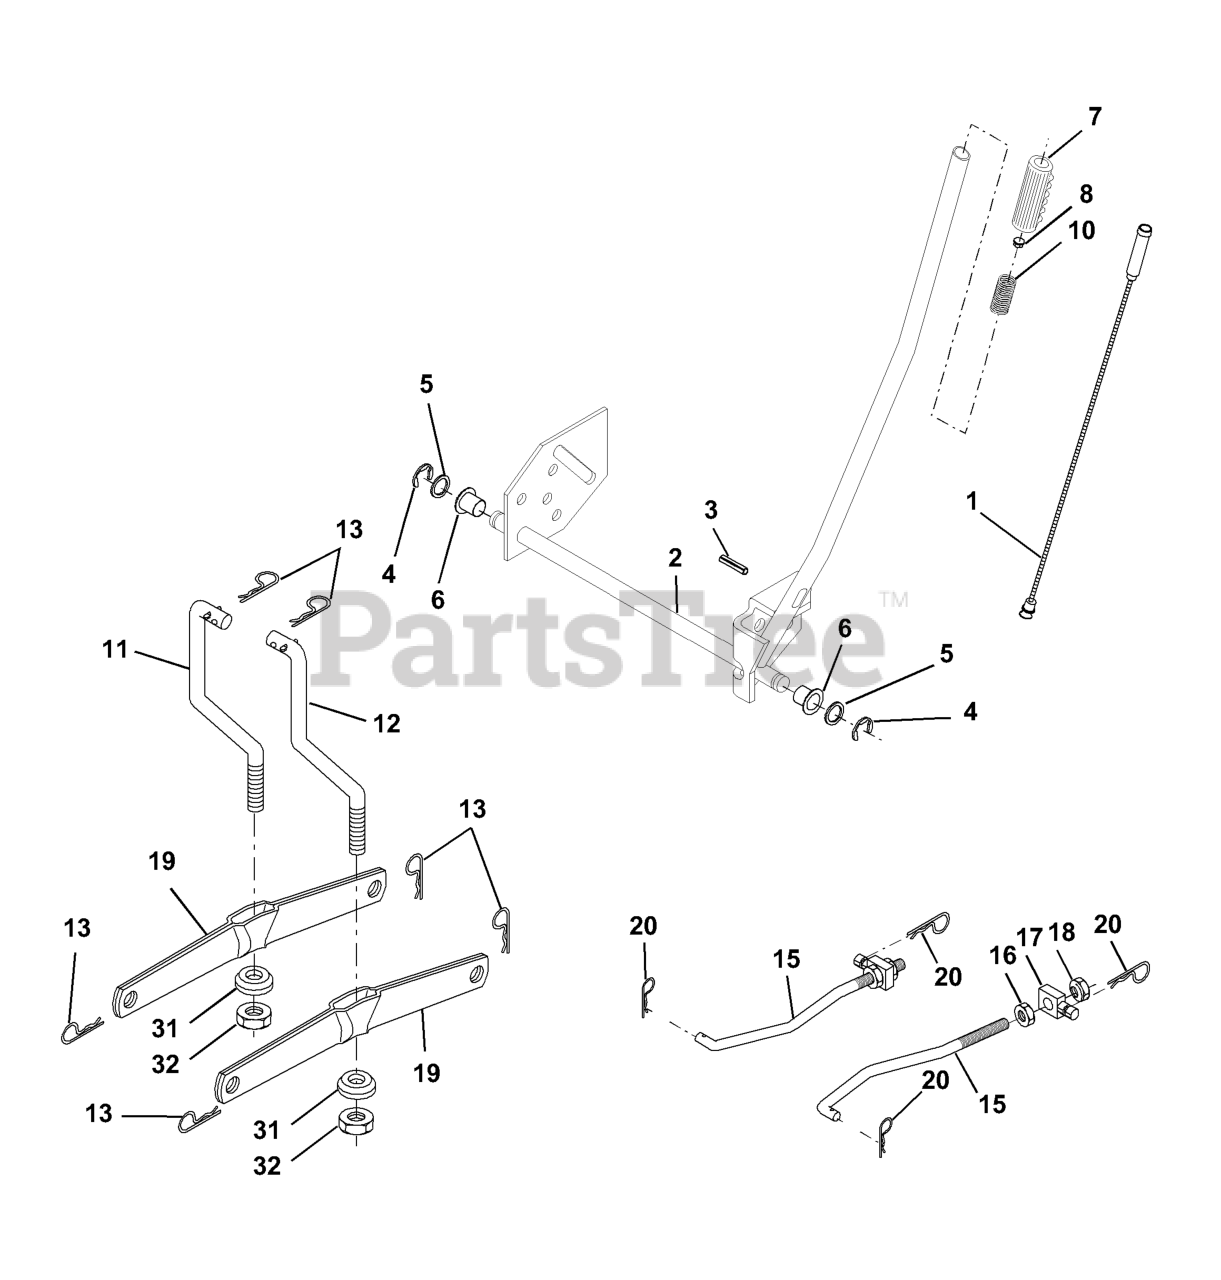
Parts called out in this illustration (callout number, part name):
1	WIRE.INNER.HANDLE.LIFT.LEVER
2	SHAFT ARM LIFT RH
3	PIN GROOVE.
4	RETAINING RING LT
6	BEARING.NYLON
8	PLUNGER BUT KIT
10	SPRING, COMP T
11	LINK LIFT LH
12	LINK LIFT RH
13	RETAINER-SPRNG RB
15	FRONT LINK
16	NUT.HEX.JAM.1/2-13
17	TRUNION
18	NUT.LK.W/WSH.1/2.
19	ARM.REAR.SUSPENSION
20	SPRING RETAINER
31	BEARING PIVOT
32	NUT CROWNLOCK 3/8-24
